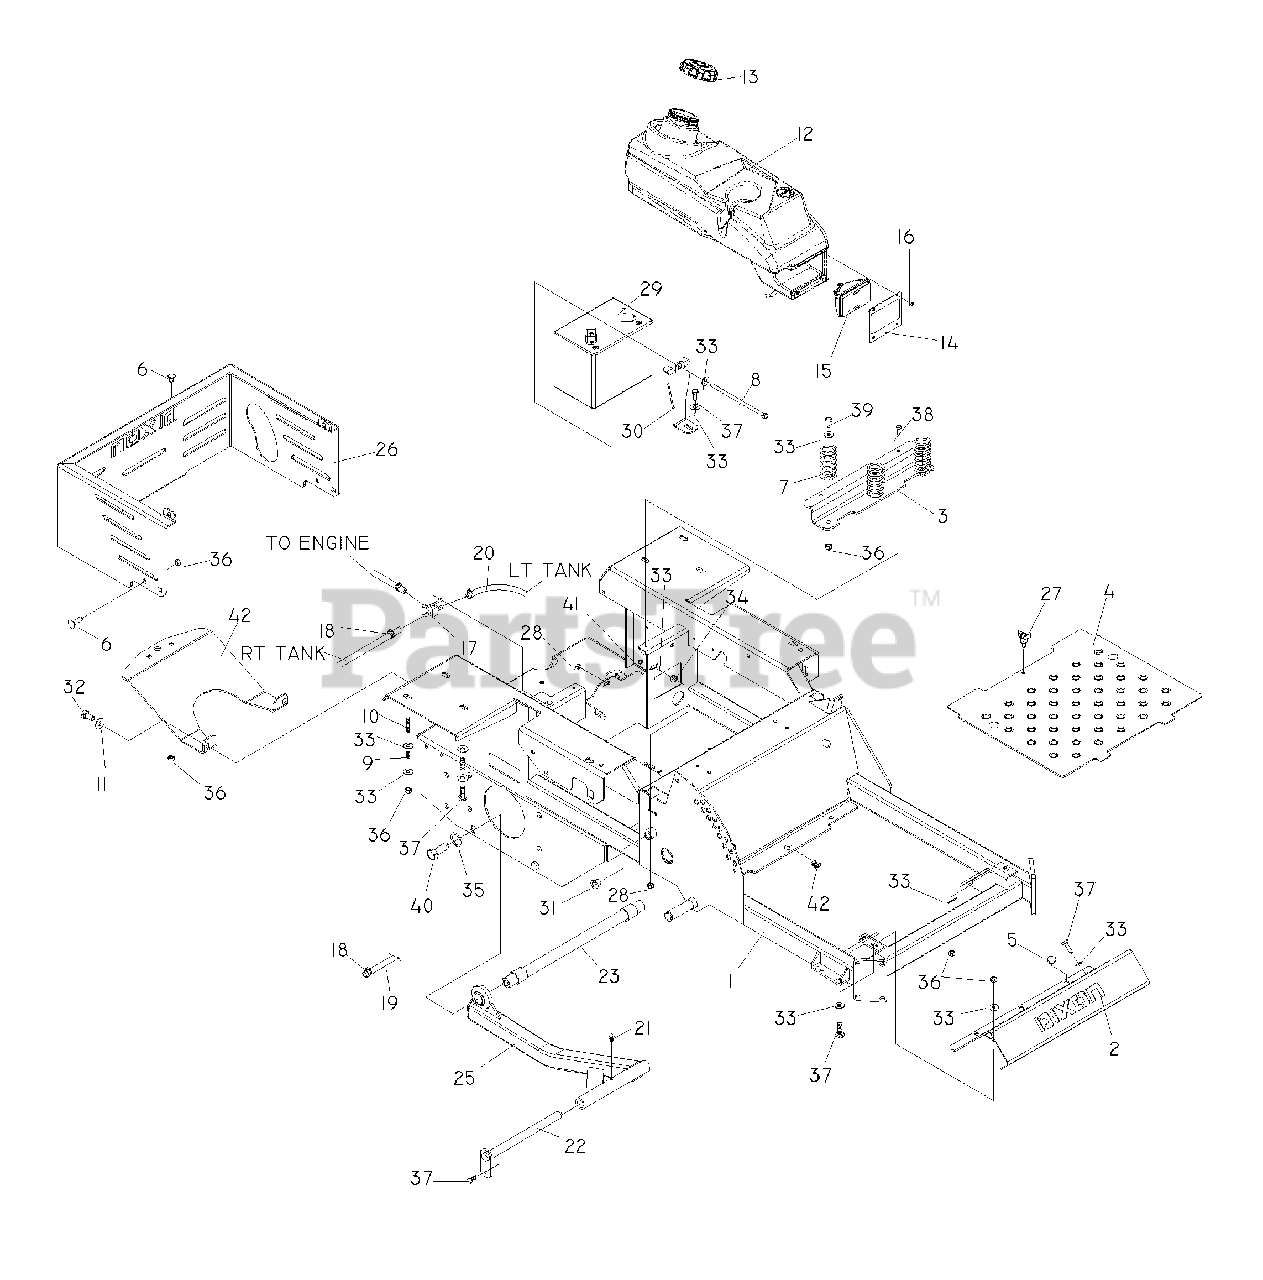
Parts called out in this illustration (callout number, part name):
1	FRAME W/DECALS KODIAK CE
2	FOOT REST
3	SPRING MOUNT
4	FOOT PLATE W/DECALS KODIAK CE
5	GROMMET, BUMPER
6	BOLT 5/16C X 3/4" CARRIAGE
7	SEAT SPRING
8	HCS 5/16-18 X 6 GR 5 ZD
10	STUD, 5/16C
11	WASHER 3/8 FLAT
12	TANK, FUEL, LT
13	FUEL CAP ANTI-SPLASH
14	PLATE LIGHT
16	SCR #10-24 X 3/8 SKT HD BLK OX
17	FUEL VALVE
18	HOSE CLAMP
19	FUEL LINE 24"
20	FUEL LINE 34"
21	ZERK
22	PIVOT PIN
23	STRUT MOUNT WELDMENT
24	PLATE, SKID
25	STRUT, RIGHT
26	GUARD, REAR W/DECALS
27	KNOB W/STUD
28	5/16-18 NYLOC FLANGE NUT
29	BATTERY, 12 V 330 AMP TBR
30	BRKT, HOLD DOWN, BATTERY
31	BUSHING
32	HCS 3/8C X 1
33	WASHER 5/16 FLAT
34	NUT 5/16C CENTERLOCK
35	LOCKWASHER 5/8
36	NUT 5/16 NYLOC
37	HCS 5/16C X 1
38	HCS 1/4C X 3/4 HCS
39	SCREW 5/16C X 1 HEX CAP
40	HCS 5/8C X 2 GR.5
41	NUT 1/4-20 NYLOC
42	U-CLIP 5/16-18 NUT RETAINER
